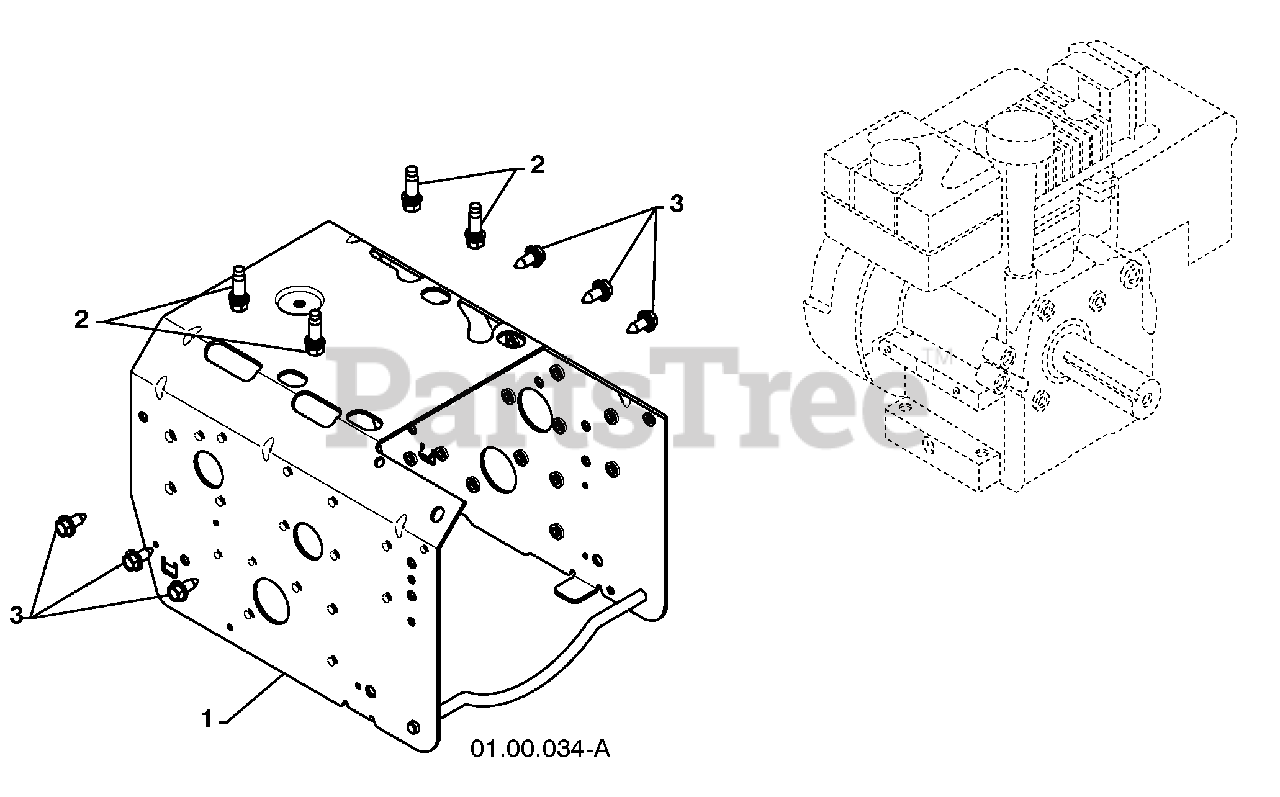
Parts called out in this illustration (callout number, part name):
1	FRAME
2	BOLT 3/8-16
3	SCREW 5/16-18 X .750
